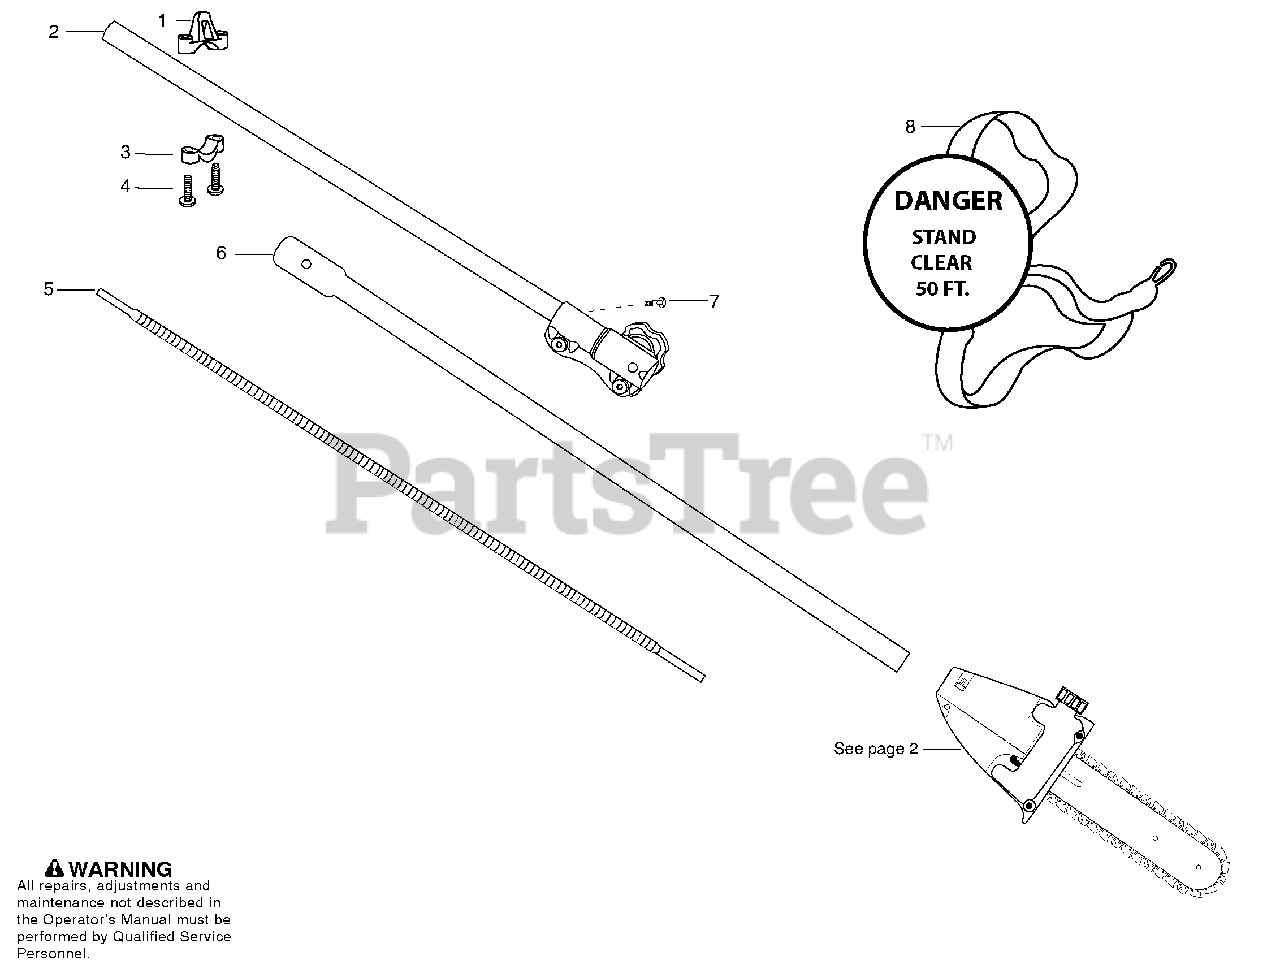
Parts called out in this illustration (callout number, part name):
1	Clamp - Harness Upper
2	Assy. - Middle Shaft
3	Clamp - Harness Lower
4	Screw (#10 plastite)
5	Flexshaft - Lower
6	Assy. - Lower Shaft
7	Screw (12-24 x .480)
8	Strap - Shoulder
